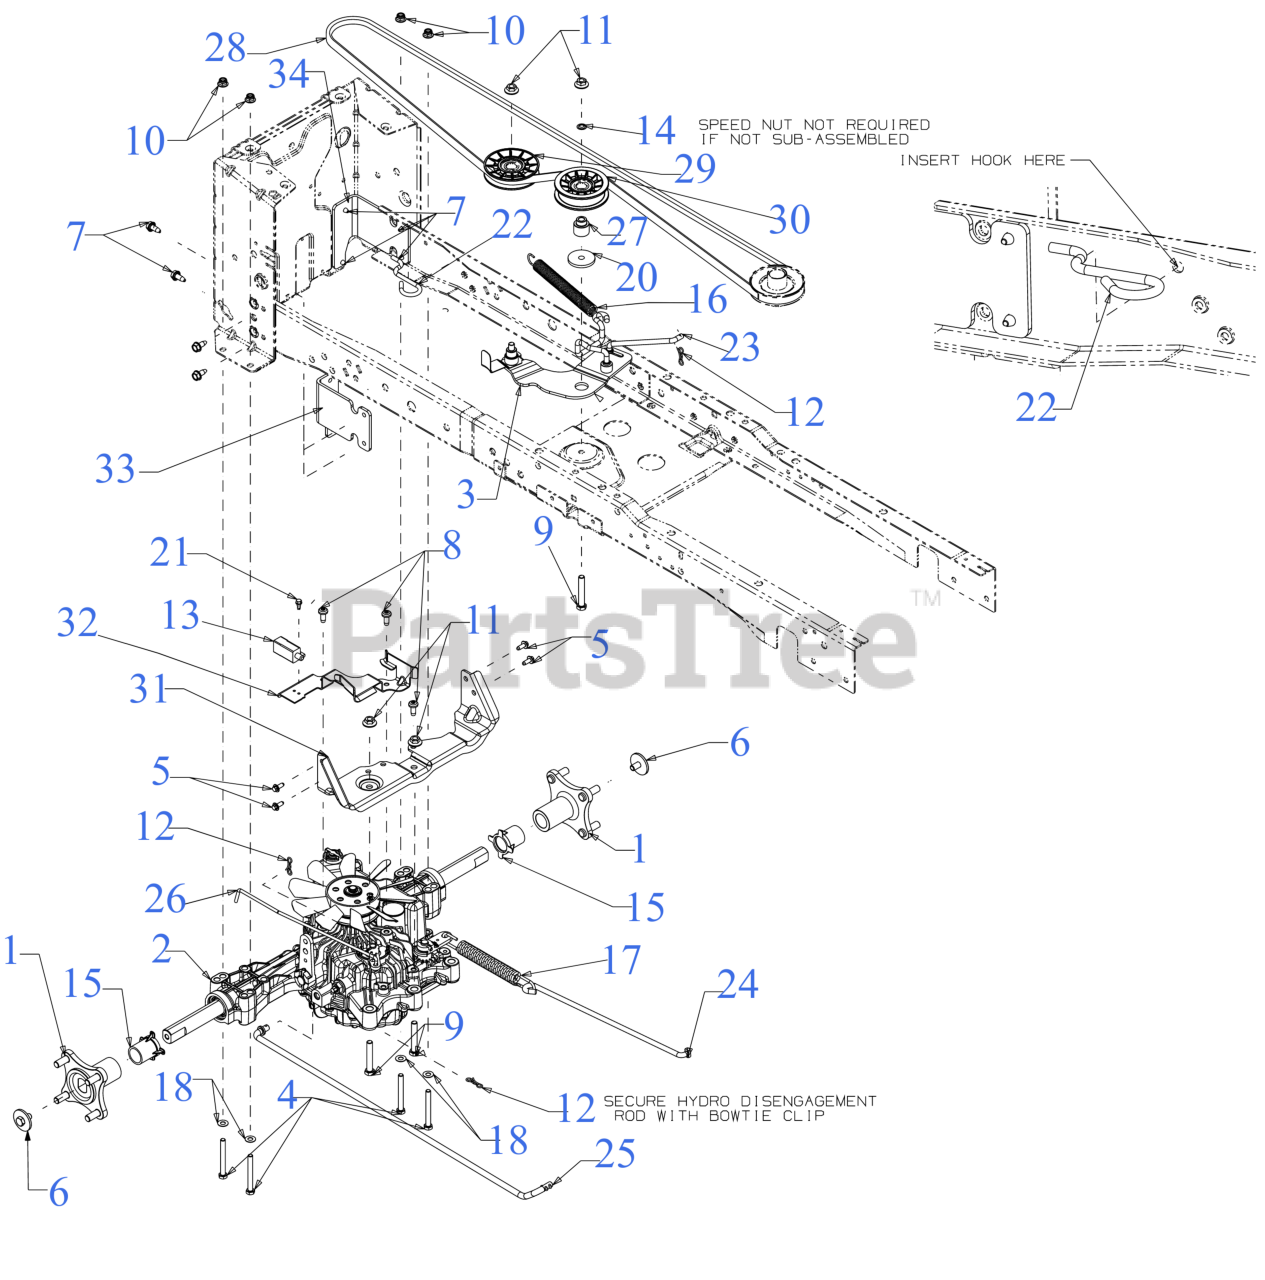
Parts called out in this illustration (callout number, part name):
1	WHEEL HUB ASSEMBLY
2	TRANSMISSION ASSEMBLY
3	IDLER BRACKET ASSEMBLY
4	HEX SCREW 5/16-18 x 2.75
5	SCREW M6-1 x .625
6	SCREW 3/8-16 x .75 GR5.1
7	SCREW M8-1.25 x .750
8	SCREW 5/16-18 x .750
9	SCREW 3/8-16 x 2.25 GR5
10	FLANGE LOCK NUT 5/16-18
11	FLANGE LOCK NUT
12	BOW TIE COTTER PIN 1/4-5/16
13	INTERLOCK SWITCH (NO/NC)
15	AXLE SLEEVE 1.02 ID x 1.60 LG
16	EXTENSION SPRING .790 DIA x 8.41
17	EXTENSION SPRING 0.90 DIA x 8.14
18	FLAT WASHER
20	SHOULDER SPACER
21	SHOULDER SCREW
22	DECK SPRING HOOK
23	IDLER BRACKET ROD
25	HYDRO CONTROL ROD
26	HYDRO DISENGAGEMENT ROD
27	SHOULDER SPACER
28	V-BELT A SEC x 90.90
28	Cub Cadet DRIVE BELT
28	Genuine Factory Parts DRIVE BELT
29	V-IDLER PULLEY 3.56 OD
30	FLAT IDLER PULLEY 3.00 OD
31	TRANSMISSION MOUNTING BRACKET
